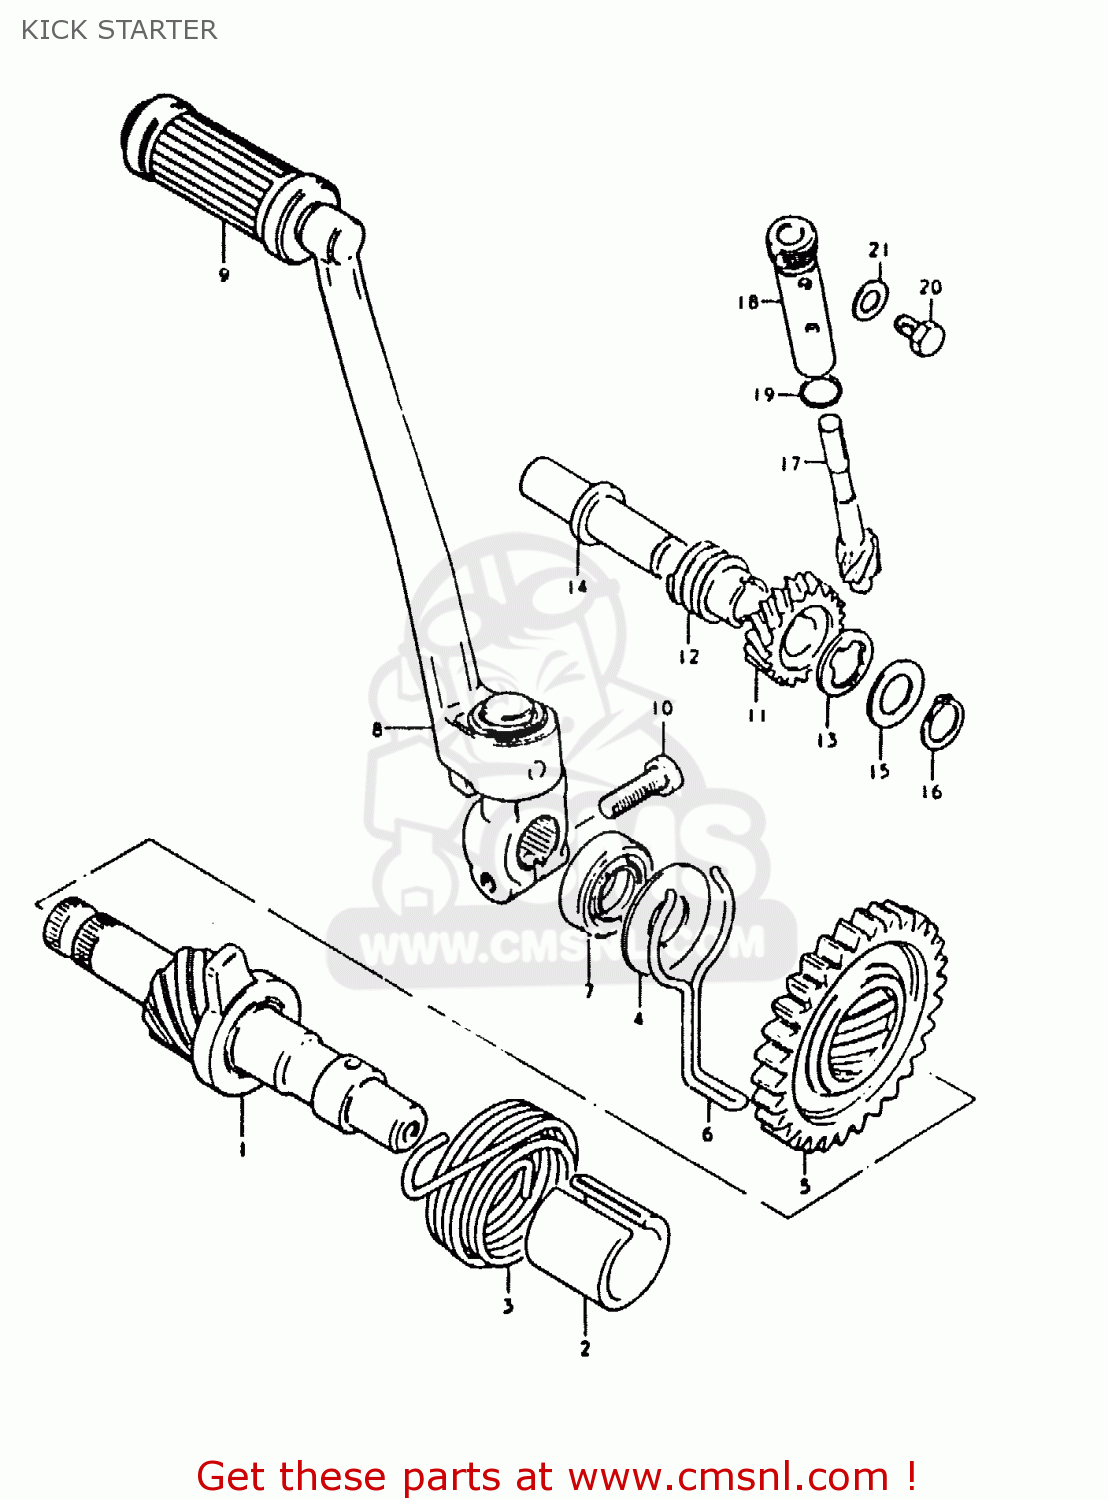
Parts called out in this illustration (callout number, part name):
1	SHAFT,KICK STARTER
2	GUIDE,KICK STARTER SFT SPRING
3	SPRING
4	WASHER
5	GEAR,KICK STARTER DRIVE(NT:30)
6	RETAINER,SNAP
7	SEAL,OIL(14X24X6)
8	LEVER ASSEMBLY,KICK STARTER
9	RUBBER,KICK STARTER PEDAL
10	BOLT
11	GEAR, TACHOMETER DRIVE NO.2
12	GEAR,TACH DRIVE NO.2(NT:3)
13	RETAINER,TACH DRIVEN GEAR NO1
14	SHAFT,TACHOMETER DRIVEN GEAR
15	WASHER,THRUST
16	CIRCLIP
17	GEAR,TACHOMETER DRIVEN(NT:12)
18	SLEEVE
19	O RING(D:1.3,ID:9.6)
20	BOLT
21	GASKET(6.2X11X1).2 (NAS)
